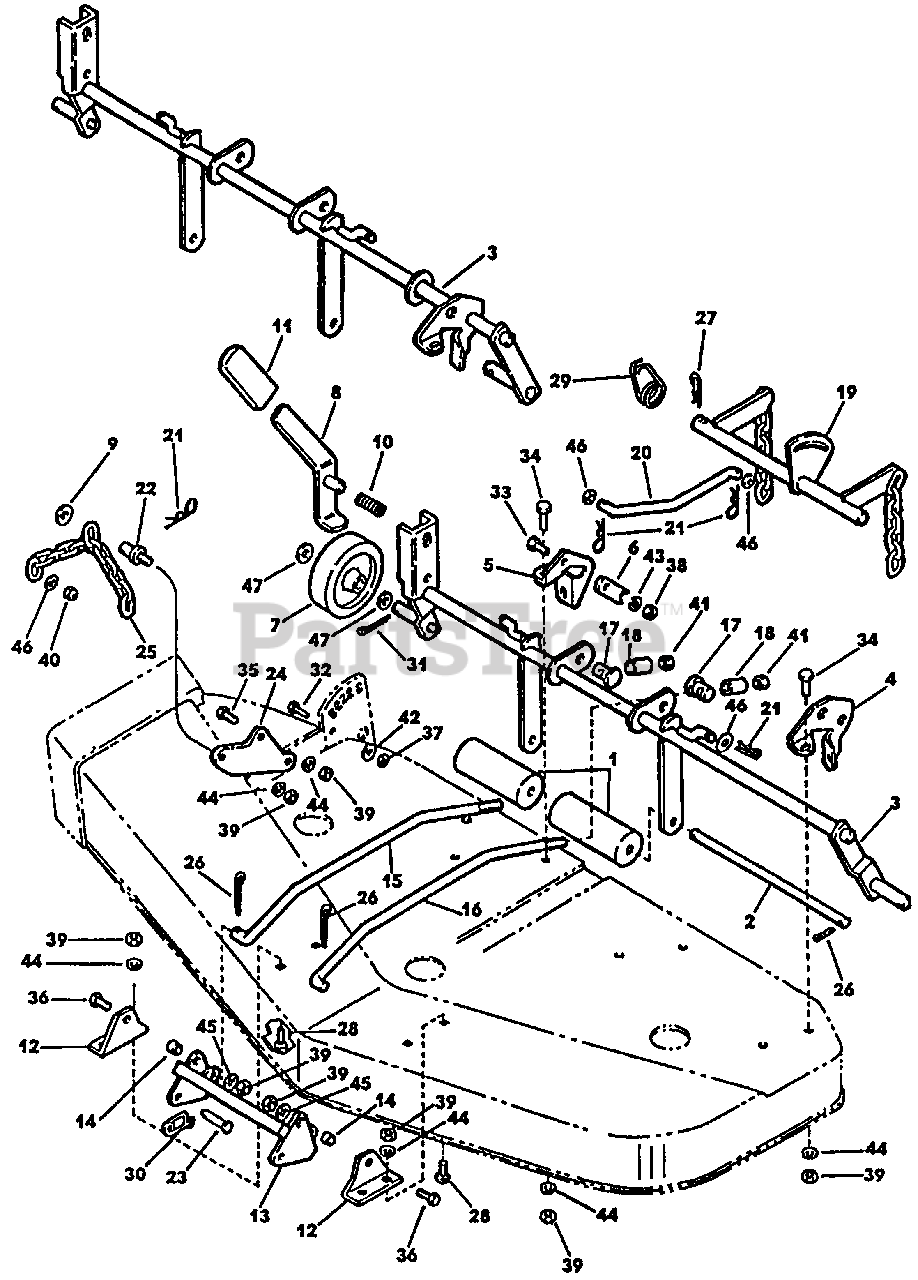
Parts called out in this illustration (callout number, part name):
1	Roller
1	Collector Housing Ass'y. w/Decals
2	Roller Shaft
2	Decal-Warning
3	Hanger Assembly, Wheel (42H Only)
3	Decal-Danger
4	Wheel Support, L.H. (42" Only)
4	Chute Collar
5	Wheel Support, Center
5	Pulley
6	Strap-Mid Support
6	Output Shaft
7	Wheel, Mower
7	Flangette Stamping
8	Handle Assembly Height Adjustment
8	Bearing
9	Washer, Flat
9	Collar w/Setscrew
10	Spring, Compression
10	Belt Retainer
11	Grip
11	Roller Chain
12	Bracket, Front Hanger
12	Sprocket-Drive
13	Front Hanger
13	Idler Sprocket
14	Bushing, Pivot
14	Spacer
15	Rod, Level-R.H. (42" Only)
15	Strip
16	Rod, Level-L.H. (42" Only)
16	Auger Assembly
17	Pin, Pivot
17	Sprocket-Auger
18	Spacer
18	Bearing
19	Bellcrank
19	Flangette
20	Link, Mower Lift
20	Washer
21	Spring Clip
21	Drive Cover
22	Lift Pin
22	Scaper Blade
23	Clevis Pin
23	Skid
24	Arm, Front Lift
24	Deflector & Decal Assembly
25	Chain, Lift
25	Decal-Danger
26	Pin, Cotter.
26	Retainer
27	Spring Clip.
27	Discharge Chute And Gear
28	Bolt, Carriage
28	Worm Shaft
29	Spring, Lift
29	Worm Gear
30	Safety Pin
30	Worm Support
31	Pin, Cotter
31	Spacer-Worm Support
32	Cap Screw, Hex Hd.
32	Snap Ring
33	Cap Screw, Hex Hd.
33	Snap Ring
34	Cap Screw, Hex Hd
34	Lock Screw
35	Cap Screw, Hex Hd
35	Lock Screw
36	Cap Screw, Hex Hd
36	Machine Screw, Hex Socket Flat Hd
37	Nut, Hex
37	Wafer Hd. Bolt
38	Nut, Hex
38	Idler Pulley
39	Nut, Hex
39	Wing Nut
40	Nut, Hex Cone Lock
40	Thread Forming Screw
41	Nut, Hex Cone Lock
41	Lock Washer #6
42	Washer, Spring Lock
42	Cap Screw, Hex Hd
43	Washer, Spring Lock
43	Cap Screw, Hex Hd
44	Washer, Spring Lock
44	Cap Screw, Hex Hd
45	Washer, Flat
45	Cap Screw, Hex Hd
46	Washer, Flat
46	Cap Screw, Hex Hd
47	Washer, Flat
47	Bolt, Carriage
48	Bolt, Carriage
49	Nut, Hex
50	Nut, Hex
51	Nut, Hex Cone Lock
52	Nut, Hex Cone Lock
53	Nut, Hex Cone Lock
54	Washer, Spring Lock
55	Washer, Spring Lock
56	Washer, Flat
57	Washer, Flat
58	Key, Woodruff
59	Key, Woodruff
60	Roll Pin
61	Set Screw, Hex Socket Hd. Cup Pt
62	Discharge Guard
63	Idler Arm
64	Spring-Idler
